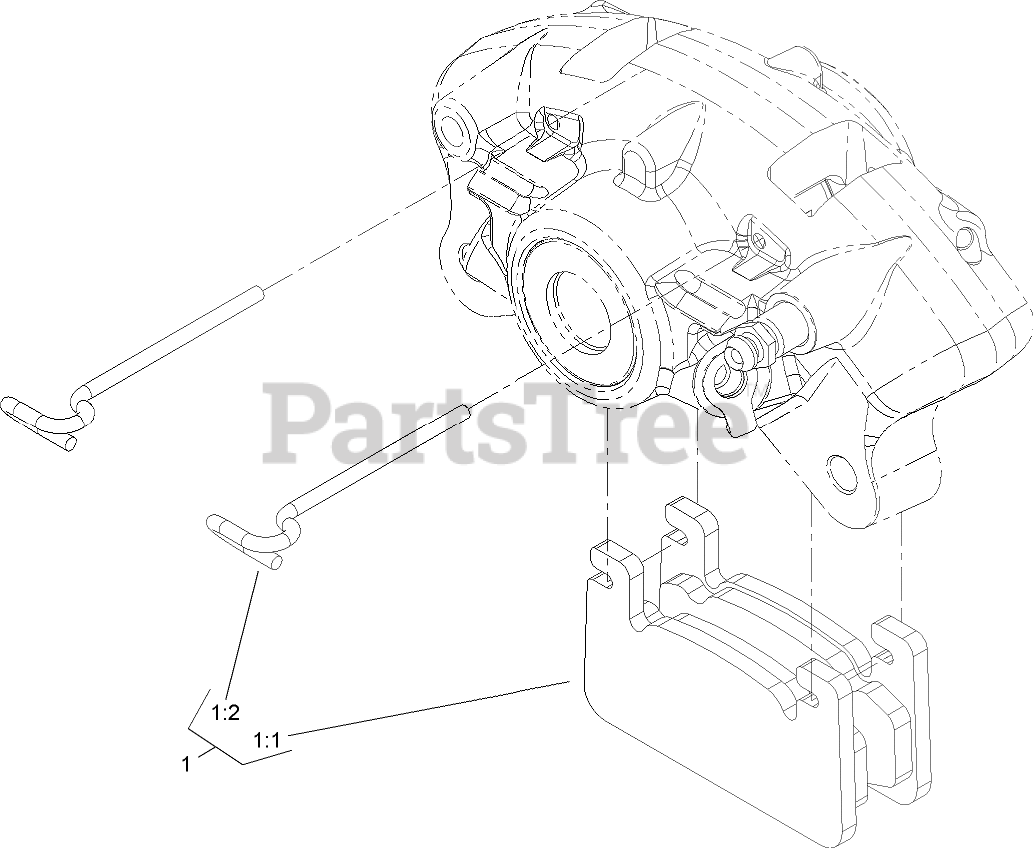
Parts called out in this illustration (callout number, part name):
1	FRICTION PAD AND PIN KIT
1:1	BRAKE PAD ASM
1:2	Pin
